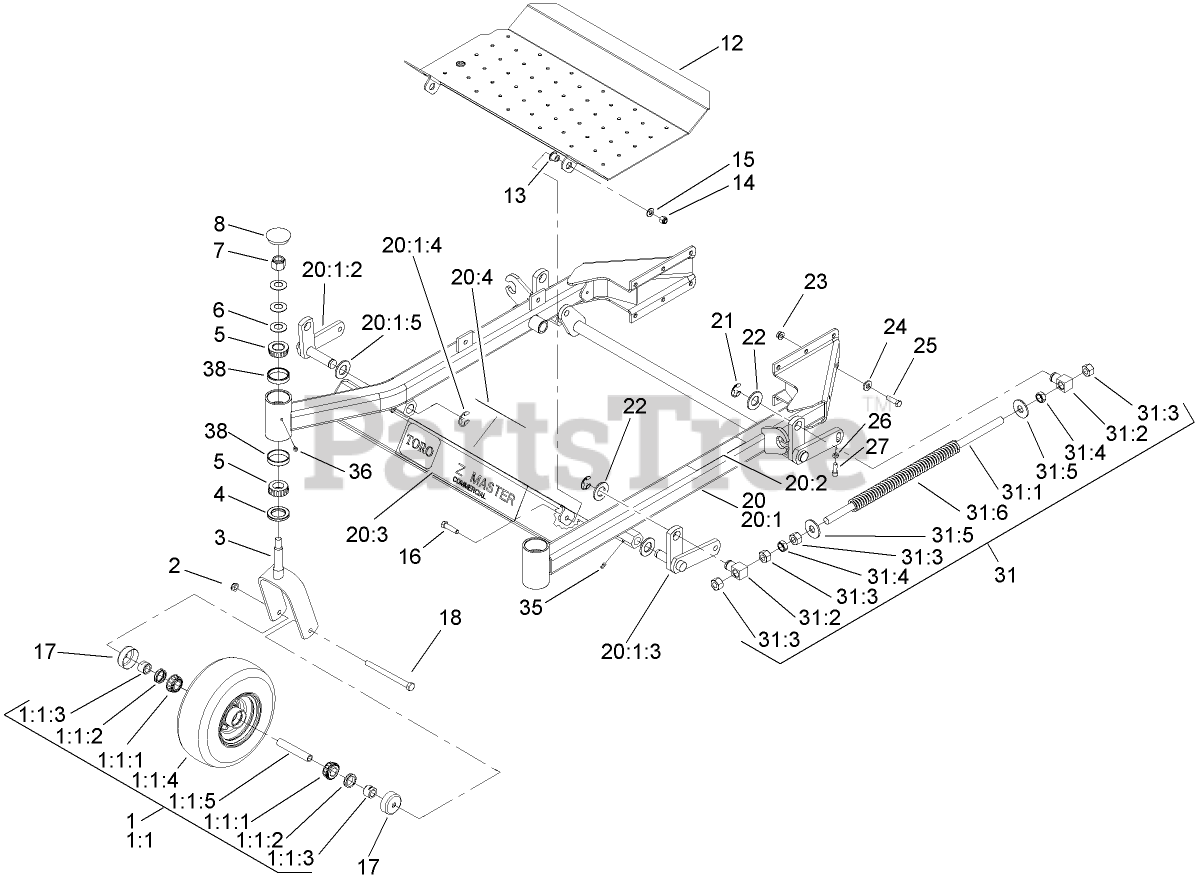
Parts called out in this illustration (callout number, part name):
1	WHEEL AND TIRE ASM
1:1	WHEEL AND BEARING ASM
1:1:1	BEARING-CONE, TAPER
1:1:2	SEAL-CASTER
1:1:3	SPACER-NUT
1:1:4	WHEEL AND TIRE ASM
1:1:5	AXLE-CASTER
2	NUT-LOCK, NI
3	CASTER FORK ASM
4	SEAL-GREASE
5	BEARING-CONE, TAPERED
6	WASHER-BELLVILLE
7	NUT-LOCK, NI
8	CAP-GREASE
12	FLOOR PAN
13	BUSHING-FLANGE
14	NUT-LOCK, NI
15	WASHER-FLAT
16	SCREW-HH
17	GUARD-SEAL
18	SCREW-HH
20	FRONT FRAME ASM
20:1	FRAME-FRONT
20:1:2	RH LIFT ARM ASM
20:1:3	LH LIFT ARM ASM
20:1:4	RING-RETAINING, EXT
20:1:5	WASHER-FLAT
20:2	DECAL-WARNING
20:4	DECAL-WARNING
20:4	DECAL-DANGER, SLOPE
21	RING-RETAINING, EXT
22	WASHER-FLAT
23	NUT-HHF, WHIZ
24	WASHER-BELLEVILLE
25	SCREW-HH
26	NUT-JAM
27	SCREW-HSH
31	FRONT FRAME SPRING ASM
31:1	ROD-LIFT, DECK
31:2	SWIVEL-DECK MOUNT, REAR
31:3	NUT-HEX
31:4	NUT-JAM
31:5	WASHER-FLAT
31:6	SPRING-SUPPORT, DECK
35	FITTING-GREASE
36	FITTING-GREASE
38	BEARING-CUP, TAPERED
